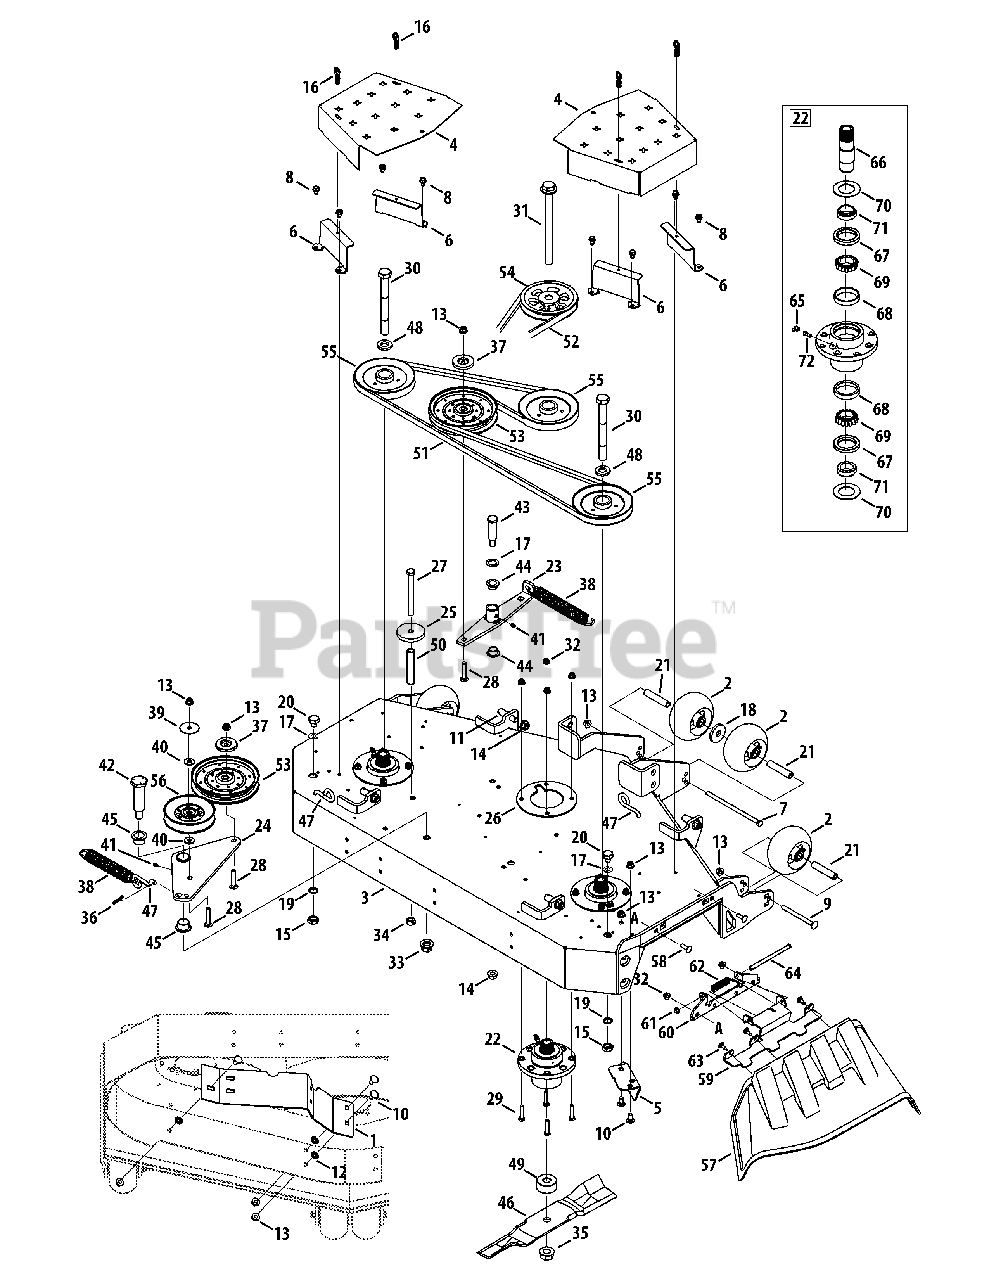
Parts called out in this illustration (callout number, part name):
1	Baffle, 48" Adjustment
2	Complete Wheel, 5.00 Dia.
4	Deck Belt Cover
6	Beck Belt Cover Bracket
7	Hex Cap Screw, 3/8-16 x 7.25
8	Screw, 5/16-18 x .500
9	Carriage Screw, 3/8-16 x 4.50
10	Carriage Bolt, 3/8-16 x .750
11	Pin, 1/2-13 x .625 x 1.2
12	Push Nut, 3/8
13	Nut, 3/8-16, Flangelock
14	Nut, 1/2-13, Flangelock
15	Hex Nut, M16-1.5
16	Folding Latch Panel
17	Washer, .793 x 1.24 x .06
18	Flat Washer, .632 x 1.00 x .160
19	Lock Washer, 17 x 23.8 x 1.95
20	Plug, Screw, M16-1.5
21	Wheel Spacer
22	Spindle Assembly
23	Deck Idler Arm
24	Idler Assembly
25	Spacer, .5375 x 2.75 x .375
26	Spindle Support Plate
27	Hex Cap Screw, 1/2-13 x 5.00
28	Screw, 3/8-16 x 2.00
29	Bolt, 5/16-18 x 1.25
30	Hex Cap Screw, 3/4-16 x 7.00
31	Hex Cap Screw, 3/4-16 x 9.00
32	Nut, 5/16-18, Flangelock
33	Nut, 5/8-18, Flangelock
34	Nut, 1/2-13, Hexlock
35	Nut, 3/4-16, Flangelock
36	Bow Tie Cotter Pin
37	Pulley Cap
38	Extension Spring, 1.248 x 8.5
39	Washer, .406 x 1.92 x .060
40	Washer, .406 x 1.00 x .105
41	Grease Fitting
42	Shoulder Bolt, 1.0 x 3.15, 5/8-18
43	Shoulder Bolt, .750 x 2.23, 1/2-13
44	Flange Bearing, .75 x .52
45	Flange Bearing, 1.00 x .75
46	Hi-Lift Blade, 17.0
47	Spring Rod Hook
48	Spacer, .812 x .218
49	Spacer, .760 x 2.00 x .925
50	Spacer, .405 x .75 x 3.875
53	Idler Pulley
54	Drive Pulley
55	Spindle Pulley
56	Idler Pulley
57	Discharge Chute Assembly
58	Carriage Bolt, 5/16-18 x 1.00
59	Chute Bracket
61	Push Cap
62	Torsion Spring
63	Shoulder Screw, 1/4-20
64	Chute Rod
65	Grease Fitting, 45 degree, 1/4-28
66	Spindle Shaft
67	Seal, Oil
68	Cup Bearing
69	Cone Bearing
70	Washer, 1.50 x 2.52 x .075
71	Ring, Seal
72	Straight Adapter Fitting
